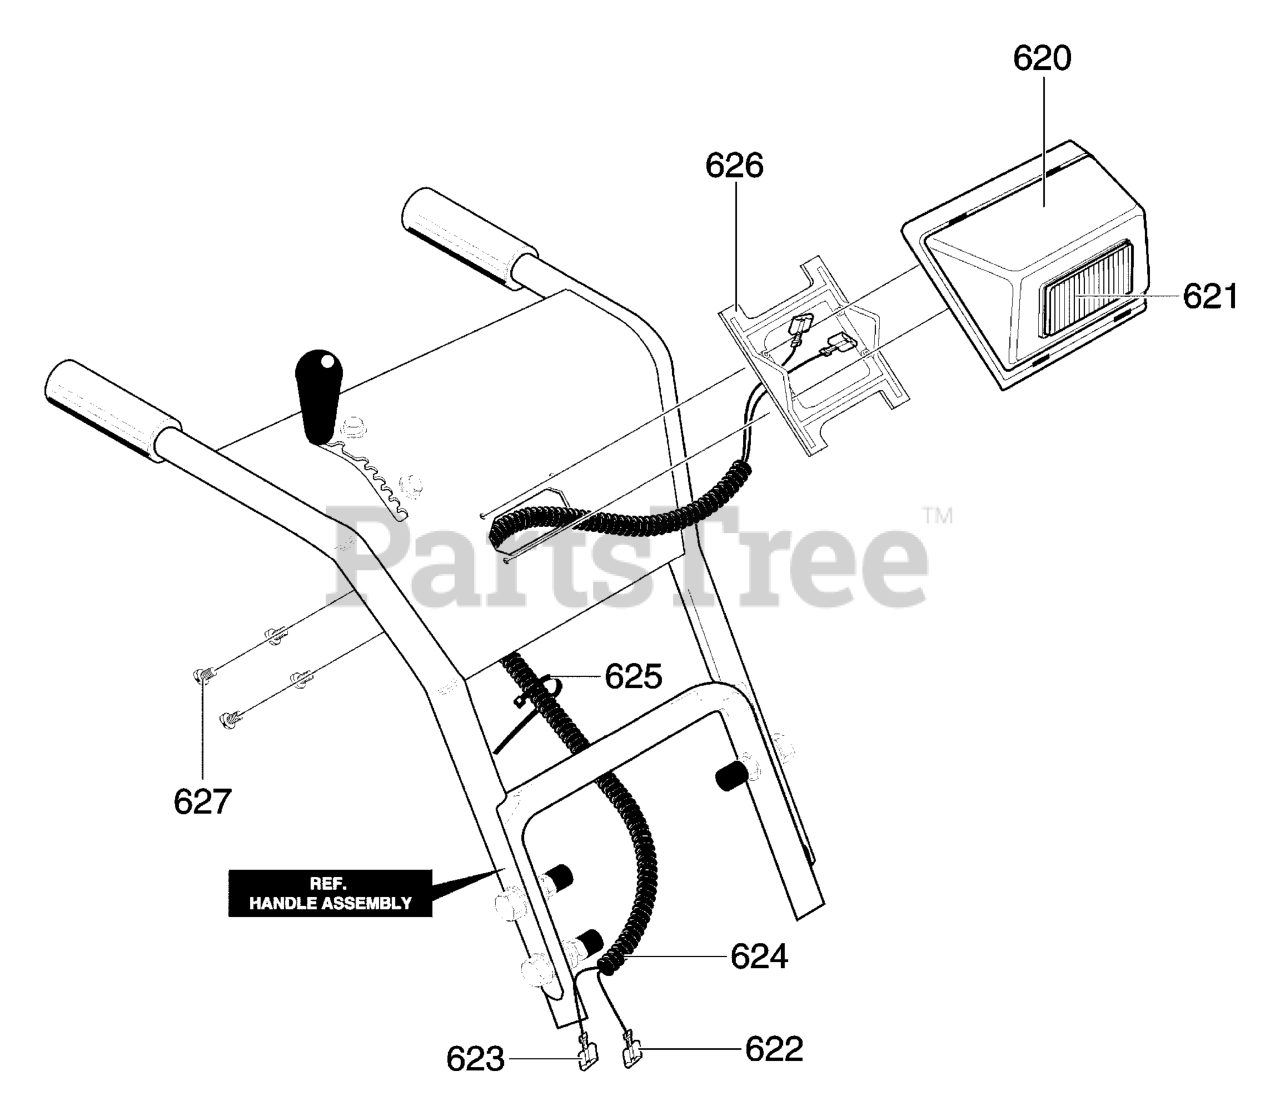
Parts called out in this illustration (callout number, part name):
620	HEADLAMP HOUSING
621	HEADLIGHT ASSY
622	LIGHT, BEZEL
623	WIRE, HEADLIGHT
624	CONDUIT, SPLIT
625	CABLE TIE
626	BRACKET, HEADLAMP
